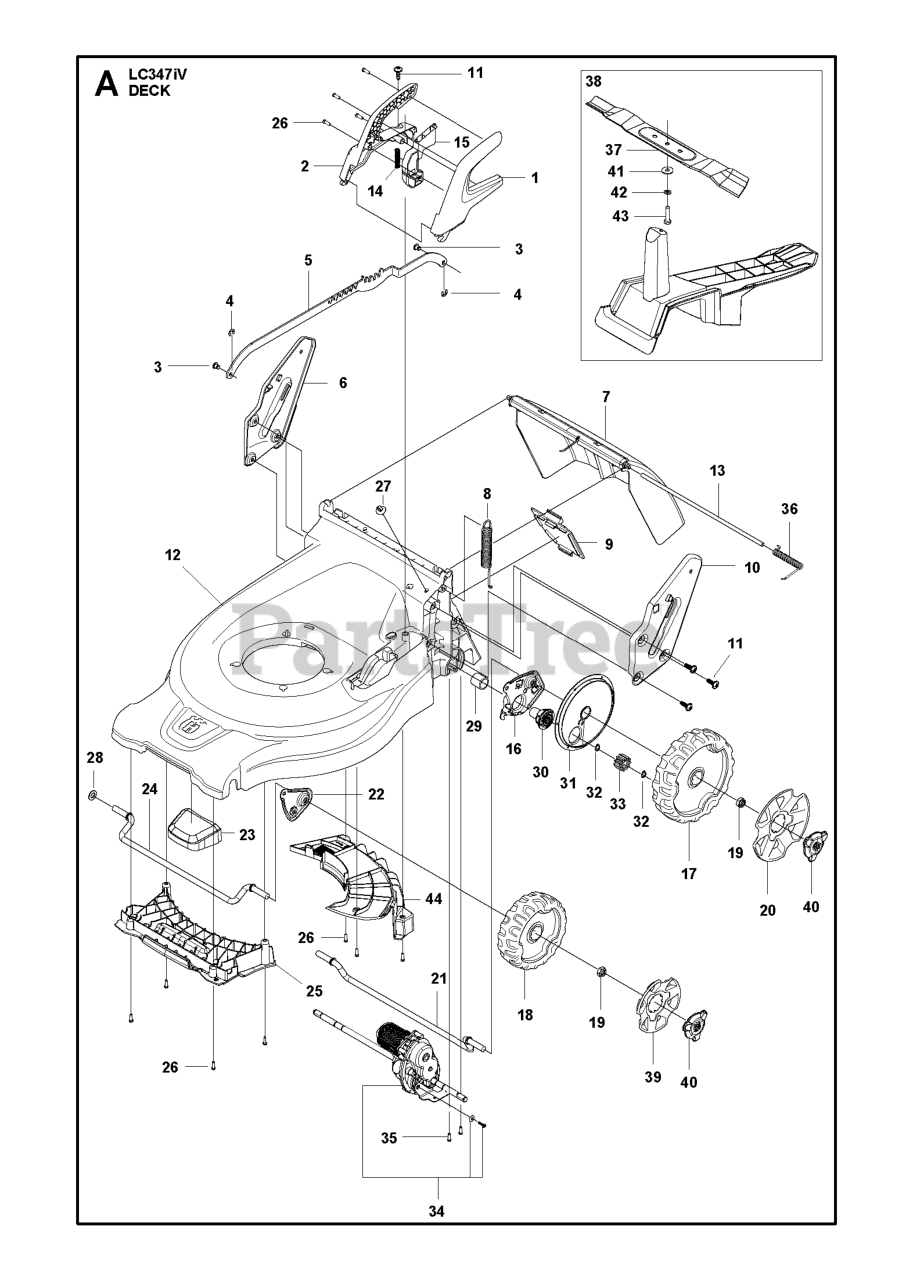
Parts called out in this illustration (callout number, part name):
4	Retaining Ring
20	HUB CAP
26	SCREW ITXPANT T50X16 ZN/FE (A
28	Washers
33	Pinions
35	SCREW ITXPANT T50X16 ZN/FE (A
40	NUT CAP
41	SPACER
42	SPRING WASHER
43	SCREW
